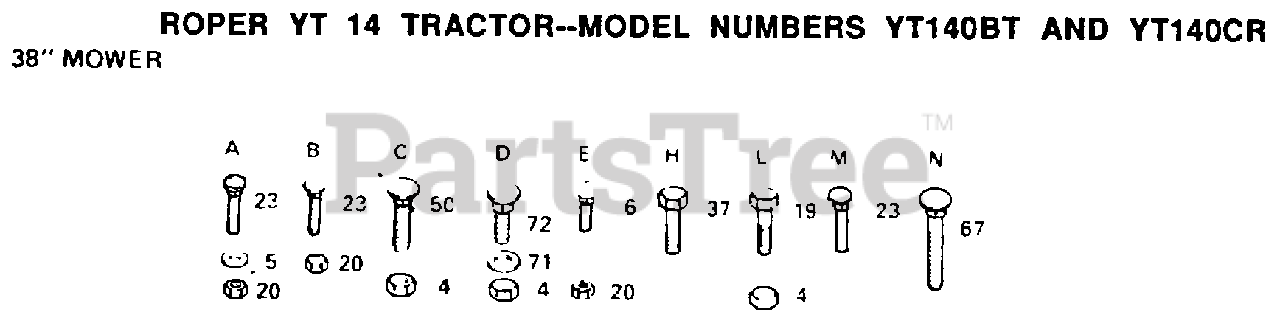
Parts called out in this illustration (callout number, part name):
5	WASHER M
6	BOLT
23	BOLT
37	SCREW
50	BOLT
67	BOLT.3/8-14X1.25
71	WASHER
72	BOLT
